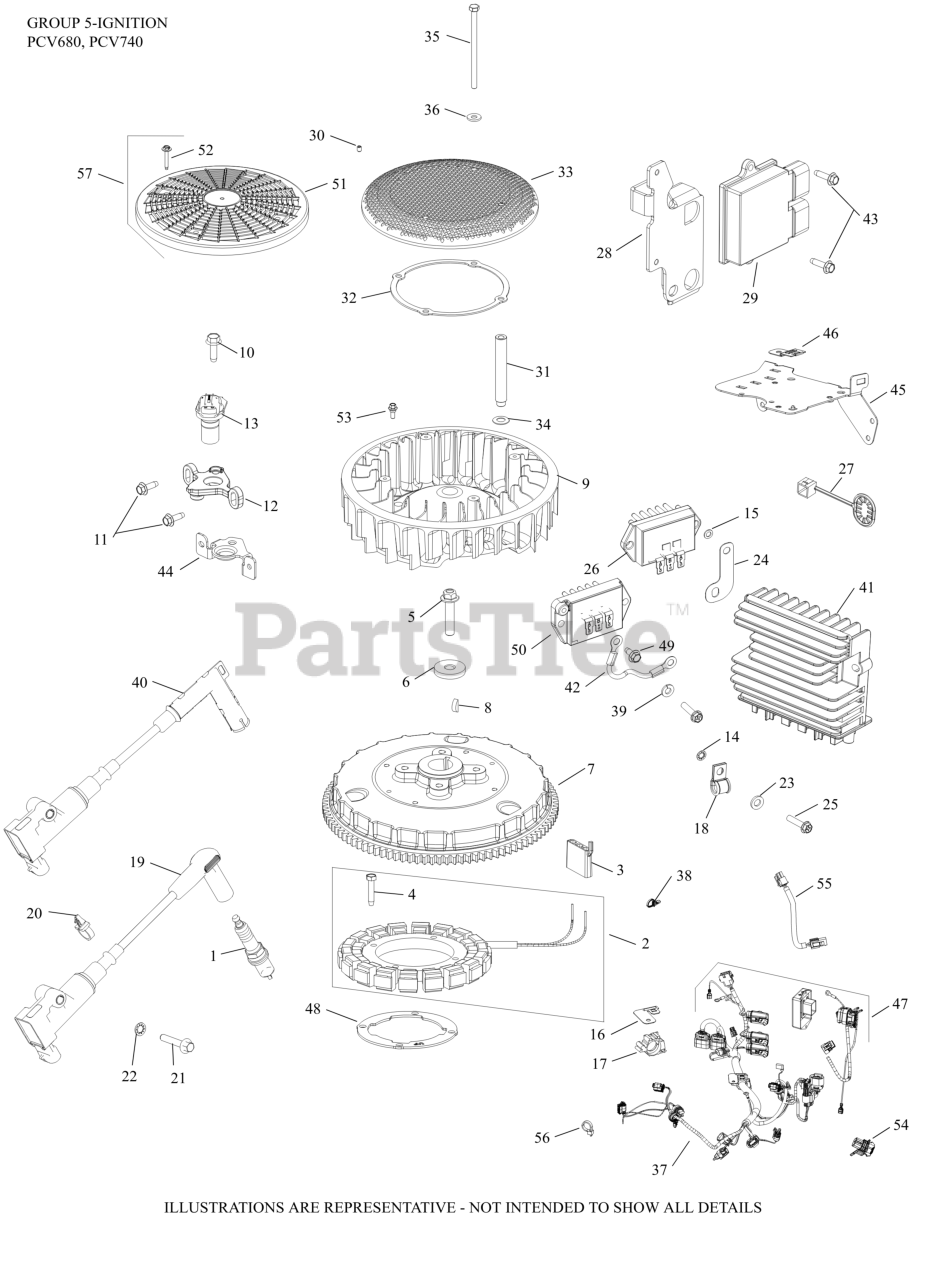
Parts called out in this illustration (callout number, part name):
1	SPARK PLUG, RFI
2	KIT, 15 / 20 AMP STATOR
3	CONNECTOR
4	SCREW, THREAD FORMING
5	SCREW, FLG M10X1.5X45-USE 25 086 361-S
6	WASHER, FLAT 13/32"
7	FLYWHEEL, ASSEMBLY
8	KEY, 3/16" X 5/8"
11	SCREW, THREAD FORMING
13	SENSOR, SPEED
14	WASHER, INT TOOTH LOCK #10
16	CLIP USE 25 154 21-S
17	KIT, MOUNTING CLIP
19	COIL, IGNITION - EFI
20	CLIP, SNAP-IN-USE 25 018 05-S
21	SCREW, FLG (BLACK) M6X1.0X34
22	WASHER, INT TOOTH LOCK 1/4"
25	SCREW, HEX FLANGE HI-LO
27	CAP, CONNECTOR
28	BRACKET, ECU
29	MODULE, ECU
30	SCREW, SKT SET #10-24X1/4"
32	RING, SUPPORT
33	SCREEN, GRASS
34	WASHER, SPRING 10 MM
35	SCREW, CAP M6X1.0X99.5
36	WASHER, FLAT 1/4" (O.D. 5/8")
44	BRACKET, SENSOR
NI	HARNESS, WIRING ASSEMBLY
NI	RETAINER, WIRE HARNESS
NI	SCREW, THREAD FORMING
NI	REGULATOR, RECT (20-30AMP, FW W/OVP)
